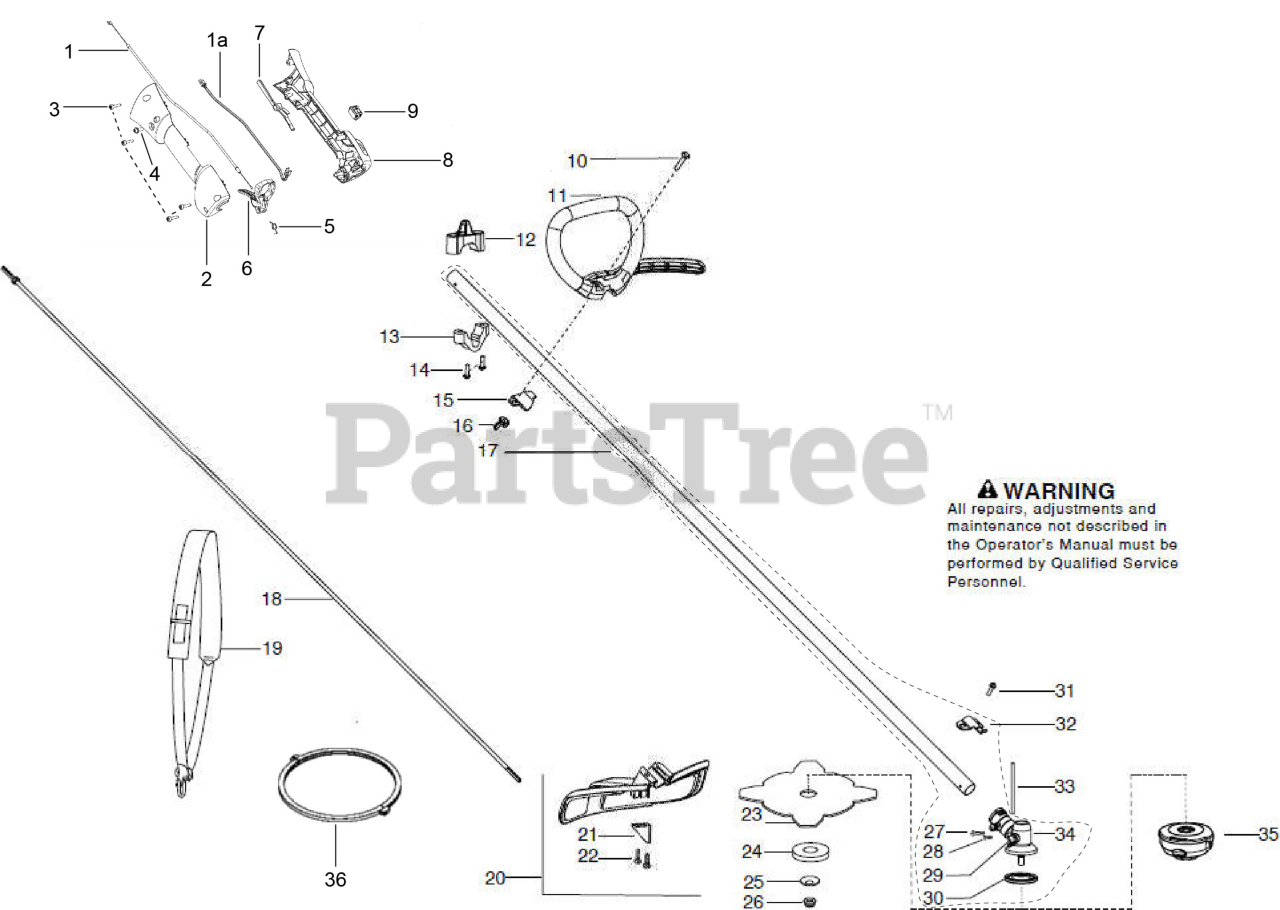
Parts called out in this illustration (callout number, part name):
1	ASSY THROTTLE
2	HSG THROTTLE RIGHT HVA
3	SCREW M4 X 1.75 PT 16MM
4	SCREW-10-14 X 1/2 PLASTITE
5	SPRING TRIGGER
6	TRIGGER THROTTLE HVA ORANGE
7	THROTTLE LOCKOUT HVA ORANGE
8	HSG THROTTLE LEFT HVA
9	SWITCH
10	BOLT, TYPE 2
11	ASSY HANDLE JBAR
12	CLAMP HARNESS UPPER
13	CLAMP HARNESS LOWER
15	CLAMP ASSIST HANDLE
16	WINGNUT, TYPE 2
17	KIT DRIVESHAFT SS BLADE
18	FLEXSHAFT 57"
19	Harness-w/o warning
20	KIT STRAIGHT SHIELD
21	Limiter - Line
23	Blade - Grass
24	SUPPORTING CUP
25	SUPPORT FLANGE
26	GEARHEAD NUT - BRUSHCUTTER
27	SCREW - CARB. ADAPTOR
29	PLUG GREASE 9MM
30	DRIVE DISC
31	SCREW 1/4-20 X 7/8 (TAP
32	BRACKET SHIELD STRAIGHT SHAFT
33	LOCKING PIN
34	ASSY GEARBOX
35	TRIMMER HEAD T25
36	BLADE GUARD TRANSPORT
